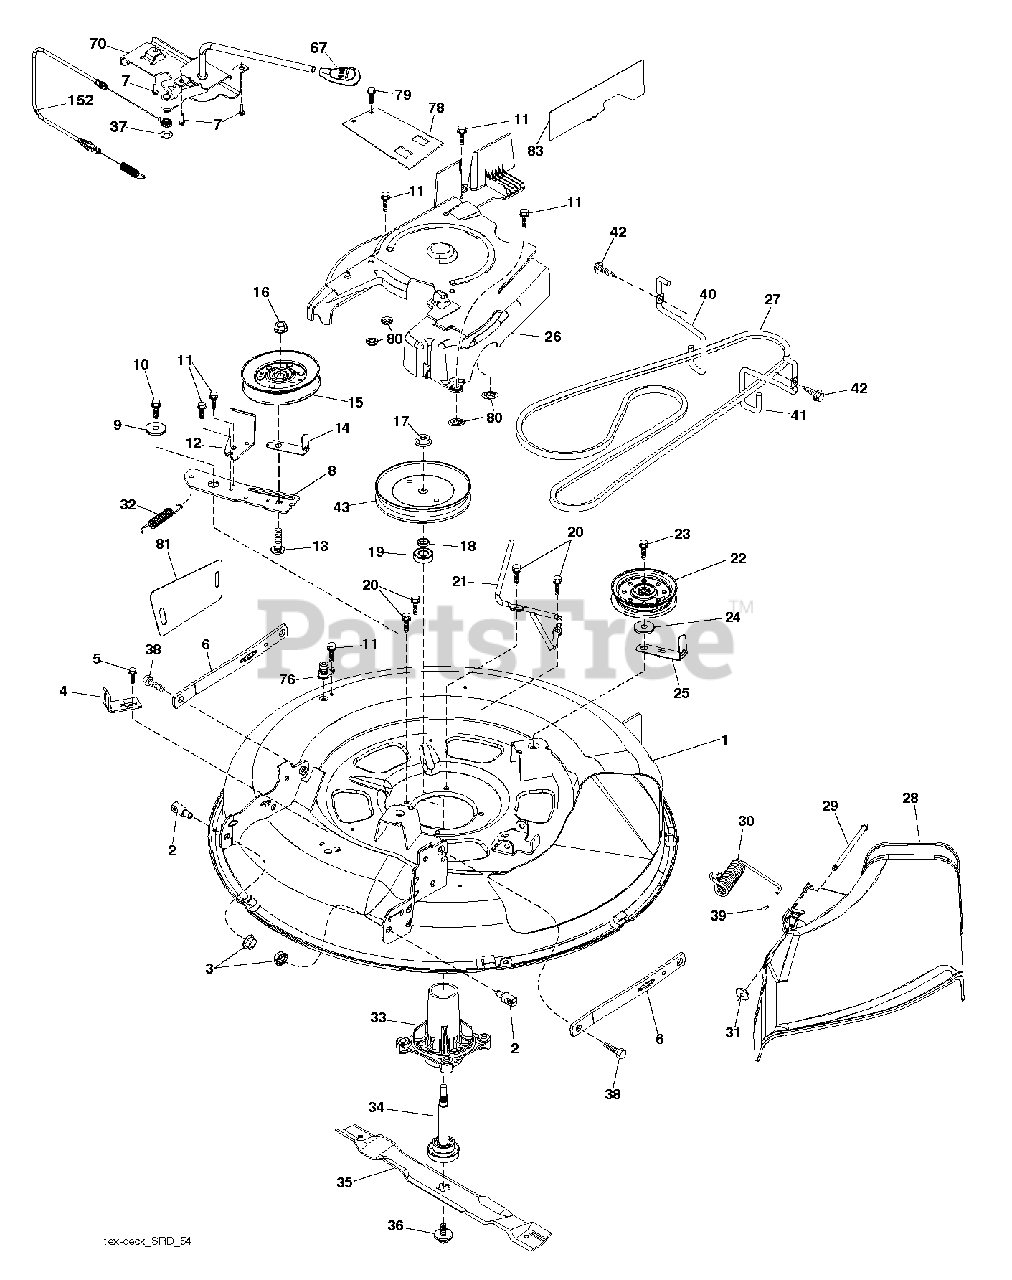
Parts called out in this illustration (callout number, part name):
1	DECK.WELDMENT.30"SRD.BLACK
2	STUD.FASTNER.W/ANTI-ROTATE
3	NUT LOCK HEX FLANGE 5/16-18
4	Clutch Cable Bracket
5	BOLT.5/16HEX.WHS.HD
6	ARMS.SUSP.MOWER.REAR.SRD
7	SCREW.#10 X 0.750.BOS THREAD
8	ARM.IDLER.30"SRD
9	SPACER.RETAINER
10	SCREW 3/8-16X1
11	SCREW.1/4-20X5/8
12	ARM BRAKE MOWER RH
13	BOLT.3/8-16X1.50
14	KEEPER, BELT IDLER
15	PULLEY.IDLER.4.25
16	NUT LOCK FLG 3/8-16 UNC
17	NUT.FLANGE.LOCK.TOP
18	WASHER.SPACER.MANDREL
20	SCREW, WASHER HEAD
21	KEEPER.BELT.MANDREL.30"
22	PULLEY.IDLER.FLAT.UNPLATED
23	SCREW LT
25	KEEPER.BELT.30"SRD
26	Mandrel Cover, 30" Deck
27	V-BELT.DRIVE.MOWER.30"
28	SHIELD.DEFLECT.MWR.30S.BLACK
29	PIN.HINGE.30".SRD
30	SPRING.TORSION.DEFLECT
32	SPRING RETURN
33	HOUSING MANDREL
34	SHAFT.ASM.MDRL.N/GREASE.38
35	BLADE, MULCH.LRV30
36	BOLT.WASHER.ASM.7/16-2
38	BOLT.SHOULDER
39	CAP-SLEEVE LT
40	KEEPER.BELT.ENGINE.LH.LT.SRD
41	KEEPER.BELT.ENGINE.RH.LT.SRD
42	SCREW, 3/8-16X3/4
43	PULLEY, MANDREL 6.5 PD
67	HANDLE.CLUTCH.CABLE.LT
70	CLUTCH.ASM.MANUAL.LT.PRED
78	GUARD ARM CLUTCH
79	SCREW.HI-LO.CONSOLE
81	SHIELD SUSPENSION
83	GUARD LEFT
152	CABLE.CLUTCH.MANUAL.
